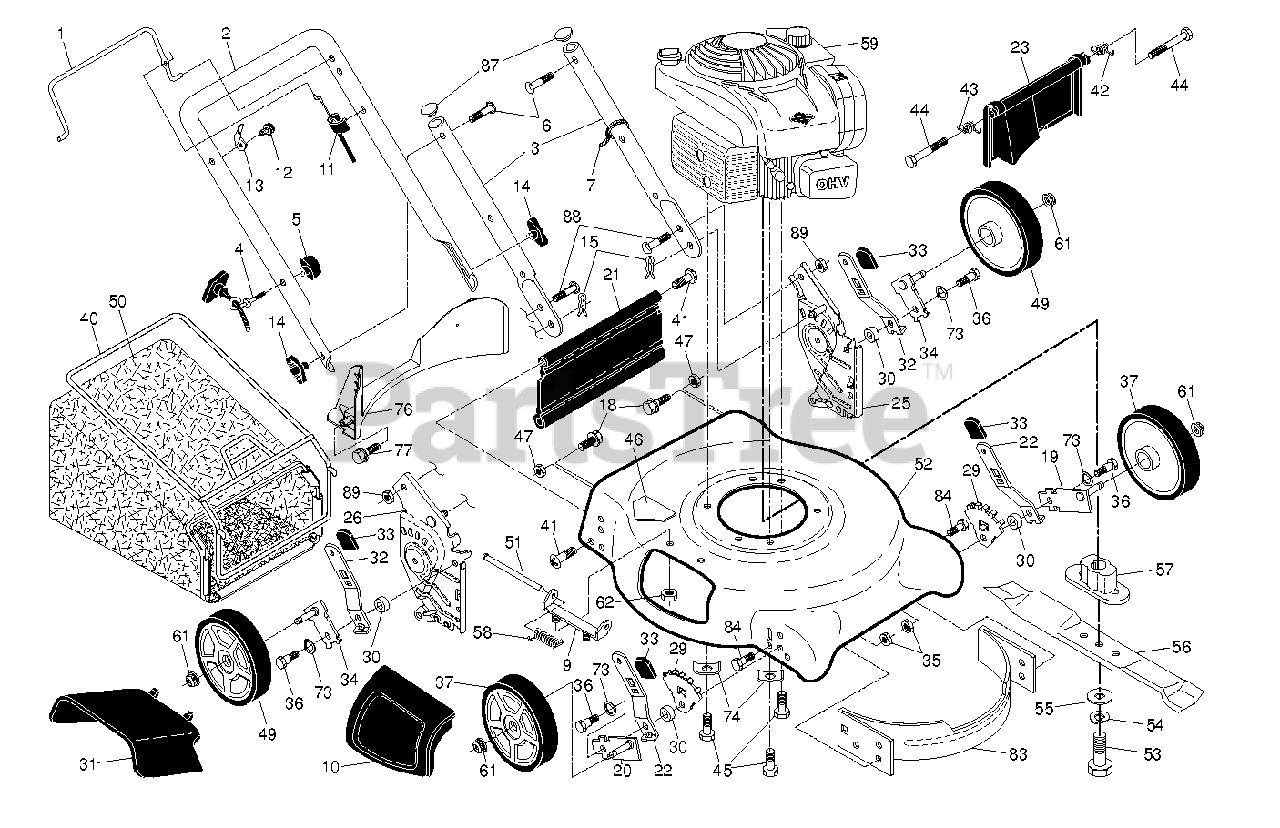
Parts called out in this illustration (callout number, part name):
1	BAIL.CONT.D.STRAIGHT.PUSH.YELL
2	HANDLE.UPPER.ECONOMY.BLACK
3	HANDLE.LOWER.DOME.BT.BLACK
4	Rope Guide, Blk Zinc Chrom
5	T-KNOB.NEW ROPE GUIDE
6	BOLT, HANDLE 5/16-18X1.75
7	TIE GUIDE
9	BRACKET.ASM.HOUSING.EZ.MUL
10	MULCH DOOR
11	CABLE.MZR.RATO.22"LOW.
13	BRACKET.UPSTOP.RT
15	HAIRPIN COTTER
18	SCREW 1/4X20
19	AXLE ARM ASSY FRONT LH
20	AXLE ARM ASSY FRONT RH
21	KIT.SKIRT.21 DOMED.W/LIP
22	SELECTOR SPRING, FRONT
23	REAR DOOR ASSY
25	BRACKET.ASM.HAND.LW.21.LT.BLAC
26	BRACKET.ASM.HAND.LW.21.RT.BLAC
29	WHEEL ADJ BRACKET FRONT
30	SPACER.HEIGHT.ADJUSTER
31	CLIP ON DISCHARGE GUARD
32	SPRING.SELECTOR.21RD.HTTRT.BZP
34	ARM.ASM.AXLE.REAR.5/9.POS.BZP
35	NUT.FLANGE.HEX.5/16X18.BLACK
36	SHOULDER BOLT 5/16-18
37	WHEEL.8X1.75.5.SPK.BRK.BLK.1
40	FRAME.BAG.21.REAR.DOMED.PUSH
41	SCREW.1/4-20X21/4.HEX.
42	SPRING.LH.22.REAR.DOOR.EZ.EMPT
43	SPRING.RH.22.REAR.DOOR.EZ.
45	BOLT 3/8-16X1-1/8
46	No Step Decal
47	NUT.71038.31-18.HEX.NYLOCK
50	GBAG.27510416S.BLK.PPR
51	ROD.HINGE.COMBI-C
52	HOUSING.21".MC.PUSH.YELLOW.E/F
53	SCREW, HEX HD 3/8-24 X 1-3/8
55	WASHER,HARDEN
56	BLADE.21.PUSH/RWGD/FWGD
57	ADAPTOR.BLADE.7/8
58	TORSION SPRING
61	NUT.HEX.FLANGE.3/8-16.LOCKNUT
62	LOCKNUT.NYLOC.1/4-20
73	WASHER.CURVED.CYLINDRICAL
74	WASHER.ENGINE.BZP
76	BAFFLE.REAR.PLASTIC.21.RD.ECON
77	SCREW.HX.13X.750
83	BAFFLE.FRONT.21.DOME.US
84	BOLT.5/16HEX.WHS.HD
87	PLUG.PLASTIC.7/8".14-20.GAUGE
89	LOCKNUT-FLANGE 5/16-18
